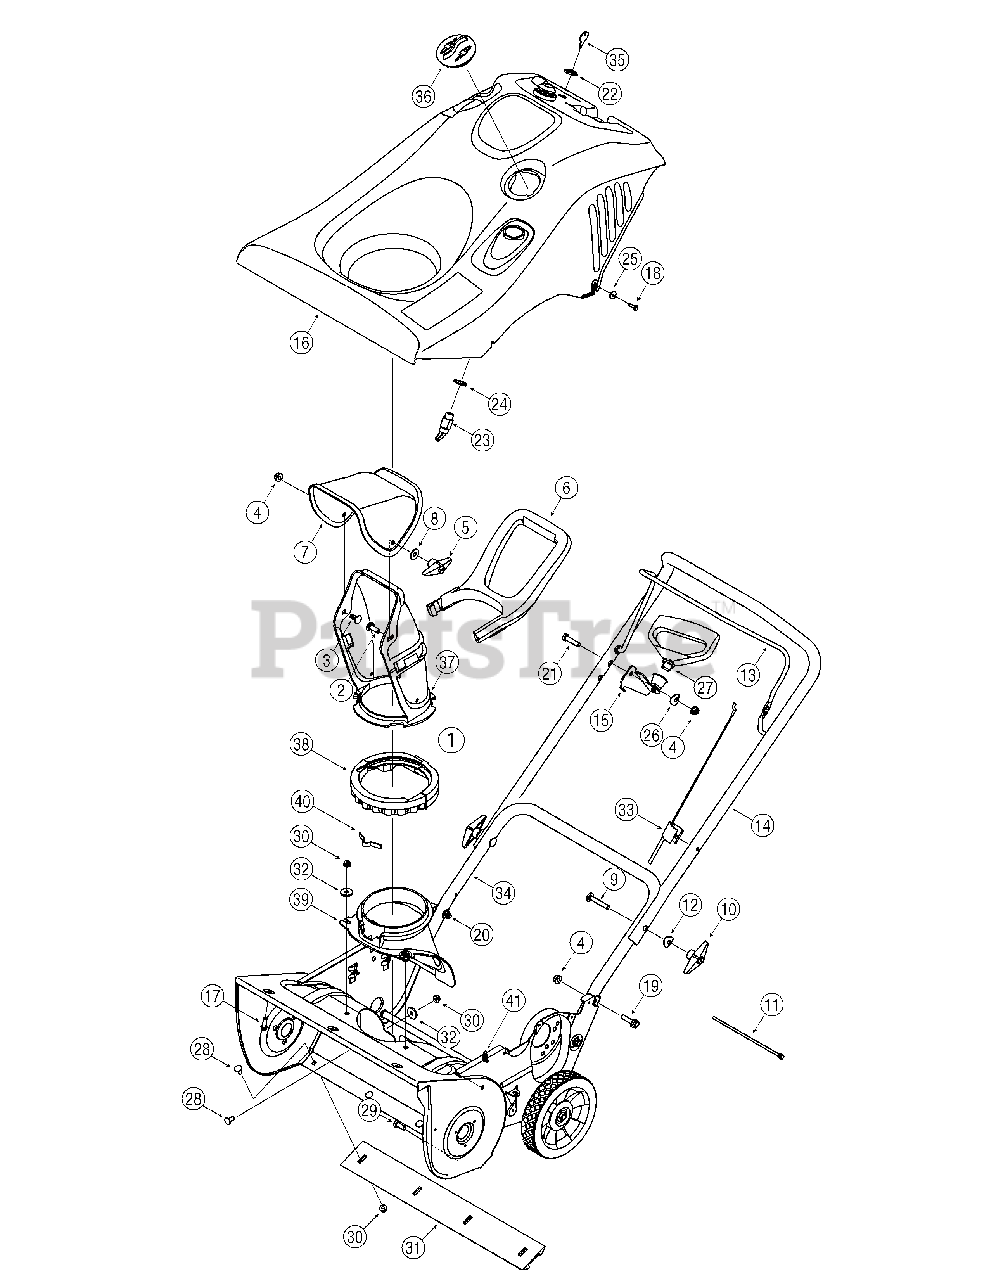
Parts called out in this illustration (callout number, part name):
1	Lower Chute Ass’y (Incl. #37-40)
2	Carriage Screw 5/16-18 x 1.0
3	Carriage Bolt 5/16-18 x .75
4	Flange Locknut 5/16-18 Gr. F, Nylon
5	Handle Knob Assembly
6	Chute Handle
7	Upper Chute
8	Flat Washer .349 ID x .879 OD x .063
9	Carriage Bolt 5/16-18 x 2.0
10	Handle Knob Assembly
11	Cable Tie
12	Saddle Wash. .320 ID x .937 OD
15	Mitten Grip Bracket Ass’y
16	Shroud Yellow, Elec. Start, w/o Crk
17	Hex Tapp Scr 1/4 x .75" Lg.
18	Hex Wash B-Tapp Scr #10 x .62" Lg.
19	Hex Scr. .312-18 x 1.250
20	Hex Scr. 5/16-18 x 1.50 Gr. 5
21	Hex Scr. 5/16-18 x 1.375 Gr. 5
22	Hex Nut 5/8-32 x .12 Special
23	Key Switch-Electric Start
24	L-Washer Internal
25	Flat Washer .218" ID x .62" OD
26	Saddle Wash. .320 ID x .937 OD
27	Recoil Handle, Mitten
28	Carriage Bolt 1/4-20 x .62
29	Hex Bolt 5/16-18 x .75" Lg. Gr. 5
30	Hex L-Flanged Nut 1/4-20 Gr. F Nylon
31	Shave Plate
32	Flat Washer .25 ID x .93 OD x .125
33	Control Cable
35	Ignition Key
36	Spark Plug Cover
37	Lower Chute 5" Dia
38	Ring-Lower Chute
39	Chute Adapter 5" Dia
40	Chute Adjustment Spring
41	Extension Spring .33 OD x 1.12 Lg.
